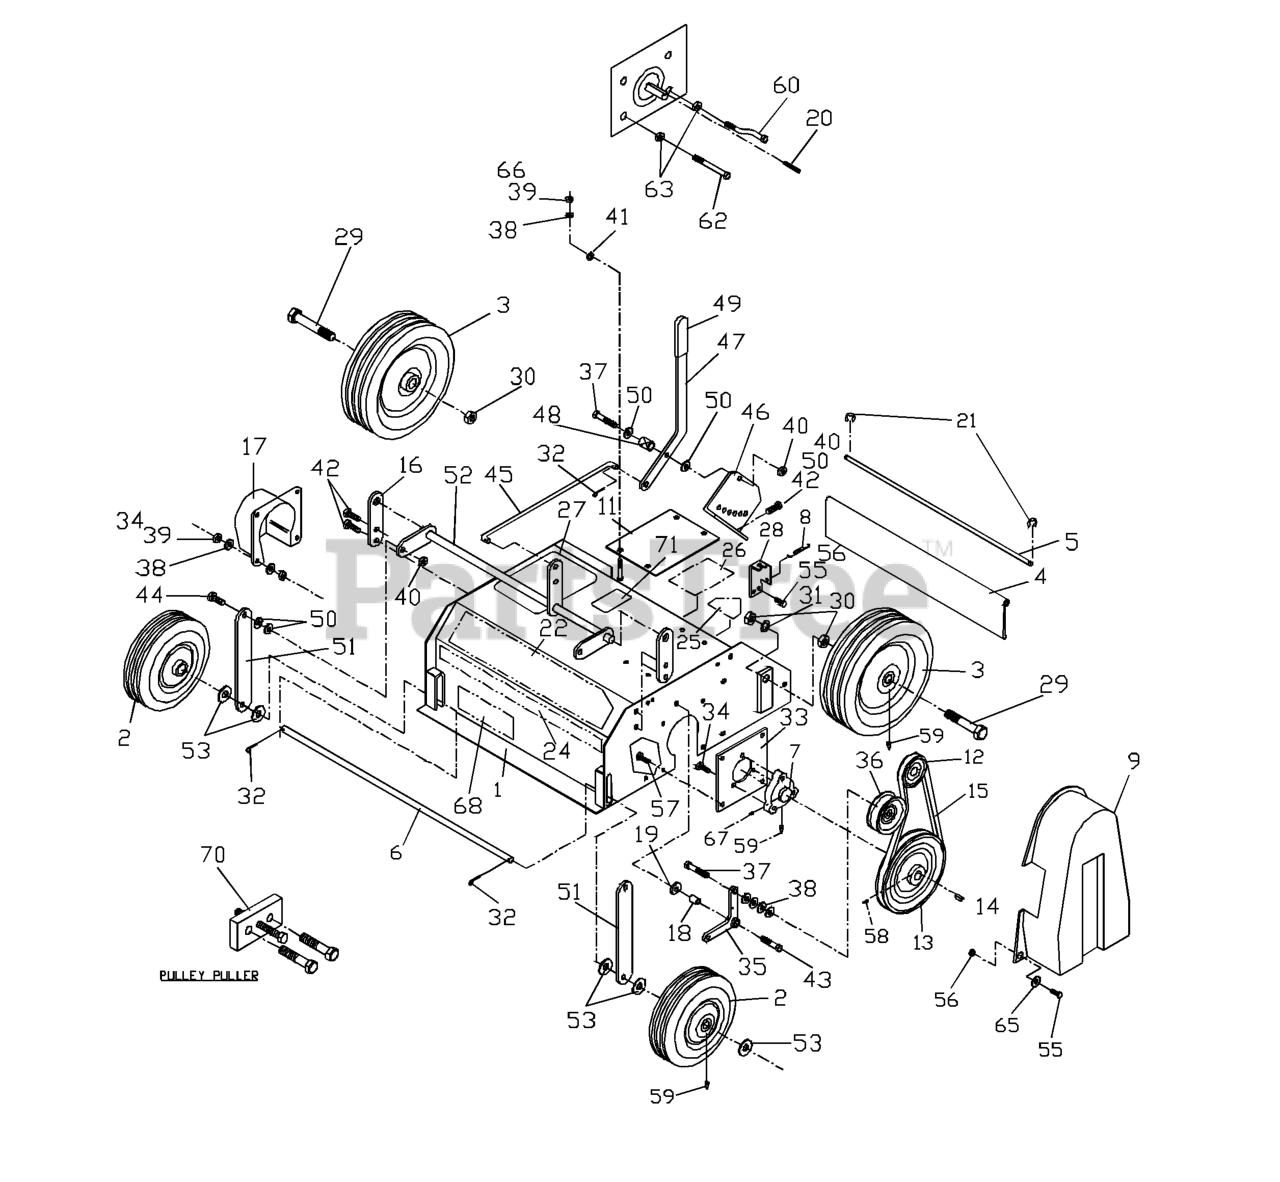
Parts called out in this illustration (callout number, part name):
1	RAKE BODY W/DECALS
1	SLICER BODY W/DECALS
2	WHEEL, FRONT
4	DEFLECTOR SHIELD
5	DEFLECTOR ROD
6	FRONT AXLE
7	BEARING, FLANGED
8	EXTENSION SPRING
9	BELT GUARD
11	PAD, ENGINE
12	PULLEY, ENGINE DRIVE
13	PULLEY, MAIN SHAFT
14	KEY, #9 WOODRUFF
15	BELT, DRIVE RAKE/SLICER DFS
17	SHAFT GUARD
18	BEARING, ONLITE RAKE/DT
20	KEY 3/16 SQUARE X 1 3/4
21	RETAINING RING 5/16
22	DECAL, HUSQVARNA 17.5"
24	DECAL, DT20
25	DECAL, CPSC
26	DECAL, WARNING
27	DECAL, ADJUSTING
28	BRACKET, CABLE
29	BOLT, AXLE 5/8-11 X 4
30	NUT JAM 5/8-11 HEX
31	LOCKWASHER 5/8
32	RP_COTTER PIN 1/8 X 3/4
34	BOLT, TAP 5/16-18
35	BELL CRANK
36	IDLER PULLEY
37	HCS 3/8C X 2
38	WASHER 5/16 FLAT
39	NUT 5/16 NYLOC
40	NUT 3/8-16 NYLOC
41	WASHER.LOCK.HVY.HLCL.SPR.5/16
42	HCS 3/8-16X1.GRD.5.ZD
43	HCS 3/8C X 1 1/2
44	HCS 3/8C X 1 1/4 GR5
45	LINKAGE ARM
46	ADJUSTMENT GAUGE
47	ADJUSTING LEVER
48	COMPRESSION SPRING
50	WASHER 3/8 FLAT
52	HEIGHT ADJ ROD
53	WASHER 1/2 FLAT
55	HCS 1/4C X 5/8
56	NUT.1/4-20.HEX.NYLOC.ZD
57	SCREW 5/16C X 1 HEX CAP
58	SET SCREW 5/16 NYLOC
59	ZERK
60	BELT GUIDE, OFFSET
62	SCREW, 5/16-24 X 2-3/4 HED CAP
63	NUT JAM 5/16F HEX
65	WASHER 1/4 FLAT
66	HCS 5/16C X 1 3/4
67	SET SCW #10-32 X 1/4
68	DECAL, NASCAR
70	PULLEY PULLER
71	DECAL, PROP. 65
